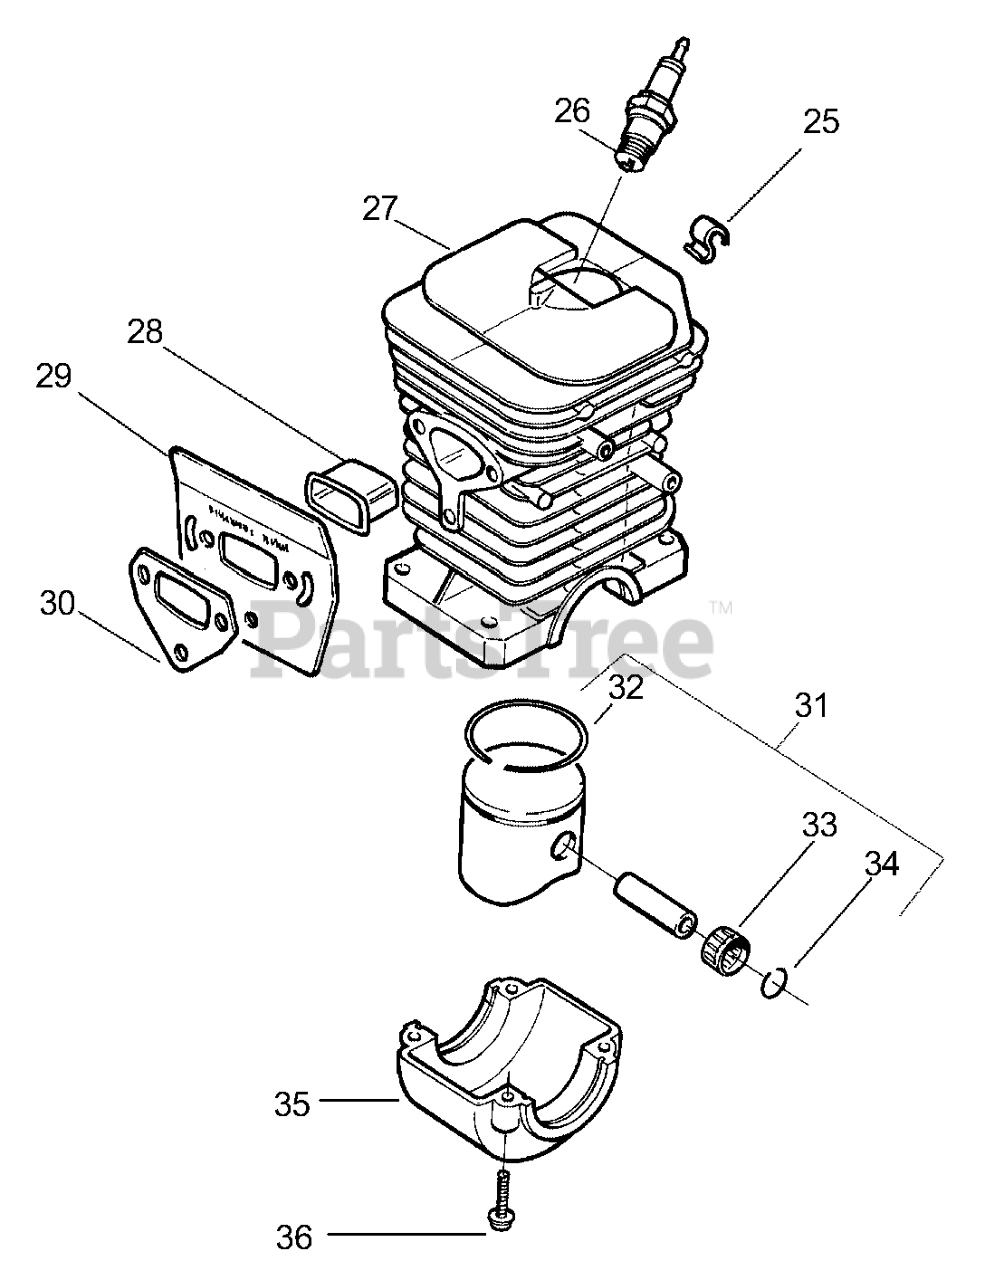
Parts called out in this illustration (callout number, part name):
25	CLIP - HIGH TENSION LE
26	Spark Plug (RCJ-7Y)
27	CYLINDER ASSY/136
27	CYLINDER ASSY/141
28	HEAT INSULATOR
29	MUFFLER PLATE
31	PISTON KIT/136
31	KIT-PISTON
32	PISTON RING 36
32	FILTER COVER OTHER - GAS L/G P
33	Piston Pin Bearing
34	C-CLIP,PSTN PIN 36/41
35	CAP-CRANKSHAFT
